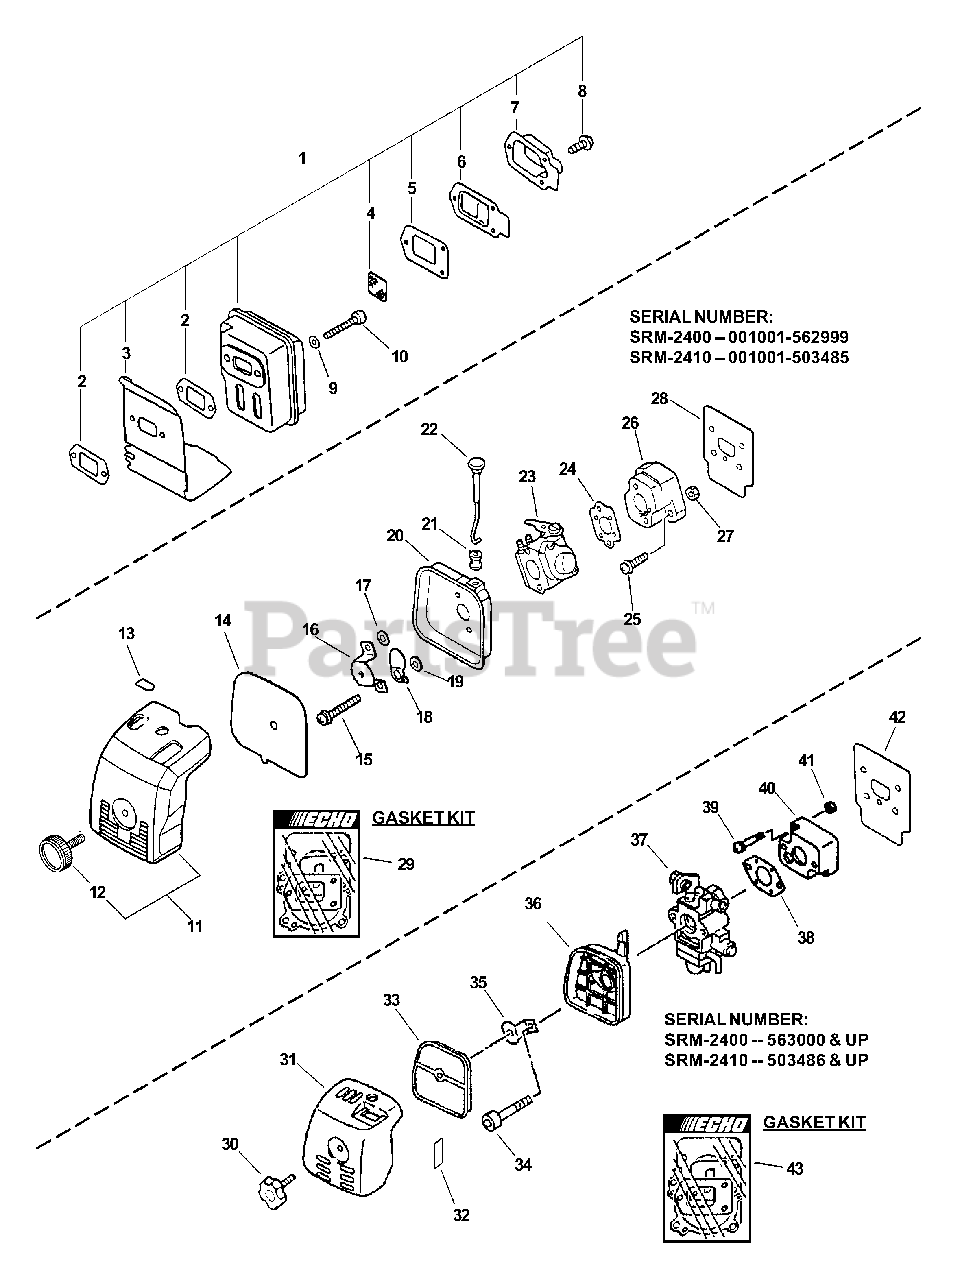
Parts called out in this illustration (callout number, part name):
1	MUFFLER ASSY
2	GASKET, EXHAUST
3	HEAT SHIELD, EXHAUST
4	SCREEN, SPARK ARRESTER
5	GASKET, EXHAUST
6	GUIDE, EXHAUST
7	OUTLET, EXHAUST
8	SCREW 4×10
9	WASHER, FLAT 5.5×10×0.8
10	BOLT 5×55
11	AIR FILTER COVER ASSY
12	THUMBSCREW
13	LABEL, CHOKE
14	FILTER, HEAVY-DUTY AIR
15	SCREW 5×57
16	PLATE, PREVENT
17	WASHER, FLAT 5.5×10×0.8
18	SHUTTER, CHOKE
19	WASHER 5.2×8×0.8T
20	CASE, AIR FILTER
21	GROMMET, CHOKE
22	ROD, CHOKE
23	CARBURETOR - WT-424A
24	GASKET, CARBURETOR
25	SCREW 5×20
26	INSULATOR, INTAKE
27	NUT M5
28	HEAT SHIELD, INTAKE
29	GASKET KIT
30	THUMBSCREW
31	COVER, AIR FILTER
32	LABEL, CHOKE
33	FILTER, HEAVY-DUTY AIR
34	SCREW 5×65
35	PLATE, PREVENT
36	CASE, AIR FILTER
37	CARBURETOR - WYJ-220
38	GASKET, INTAKE
39	SCREW 5×20
40	INSULATOR, INTAKE
41	NUT M5
42	HEAT SHIELD, INTAKE
43	GASKET KIT
